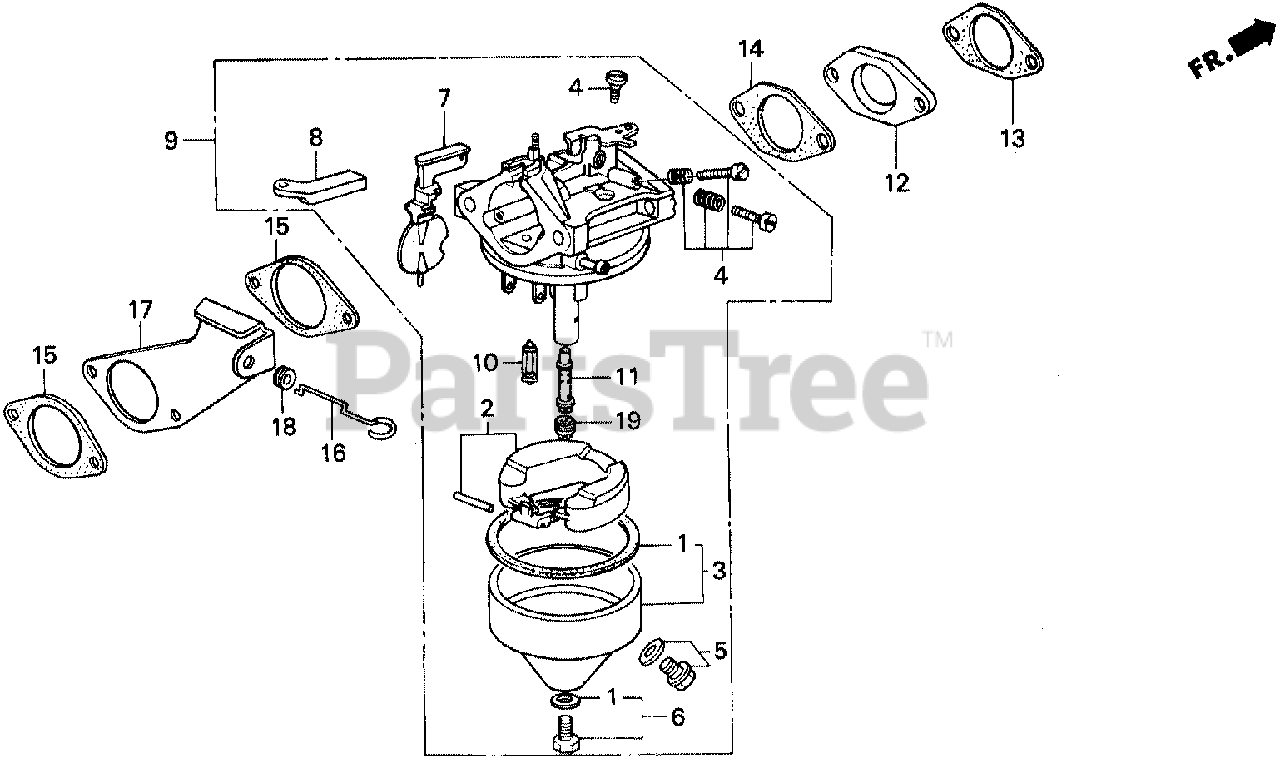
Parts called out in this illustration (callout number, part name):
1	GASKET SET
3	CHAMBER SET, FLOAT
4	SCREW SET A
6	SCREW SET B
8	ARM, CHOKE LEVER
9	CARBURETOR ASSY.
10	VALVE, FLOAT
11	NOZZLE, MAIN
12	INSULATOR, CARBURETOR
13	GASKET, INSULATOR
14	GASKET, CARBURETOR
15	GASKET, AIR CLEANER
16	ROD, CHOKE CONTROL
17	STAY, CHOKE CONTROL
18	GROMMET, CHOKE ROD
19	JET, MAIN (#68)
19	JET, MAIN (#70)
19	JET, MAIN (#72)
